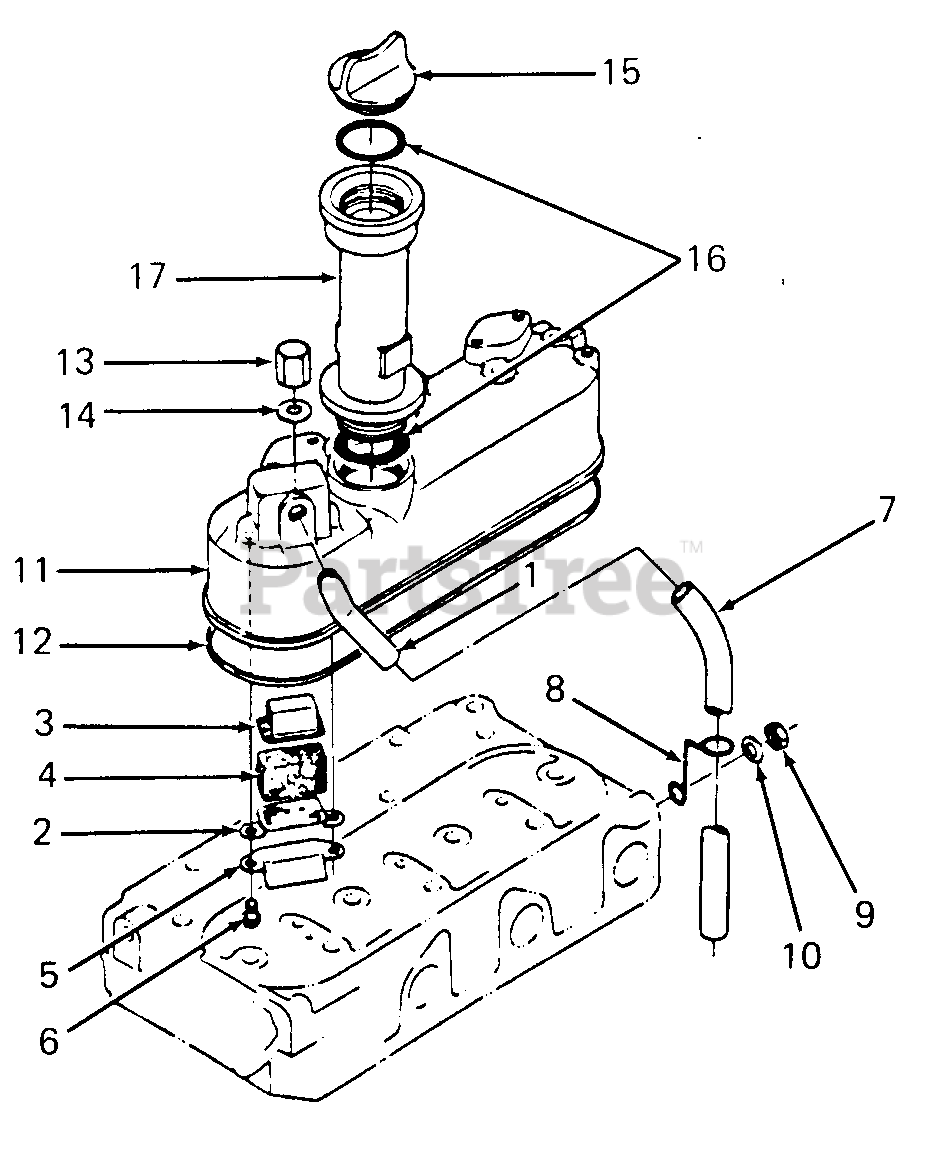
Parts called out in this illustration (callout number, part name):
1	Joint, Breather Pipe
2	Plate, Breather Element - 1
3	Plate, Breather Element - 2
4	Element, Breather
5	Shield, Breather Oil
6	Screw, Hex Cap w/Washer
7	Tube, Breather, 15.75 Lg
12	Gasket, Head Cover
15	Plug, Filler
16	O-Ring, 1-3/16 X 1-7/16
17	Extension, Oil Fill
